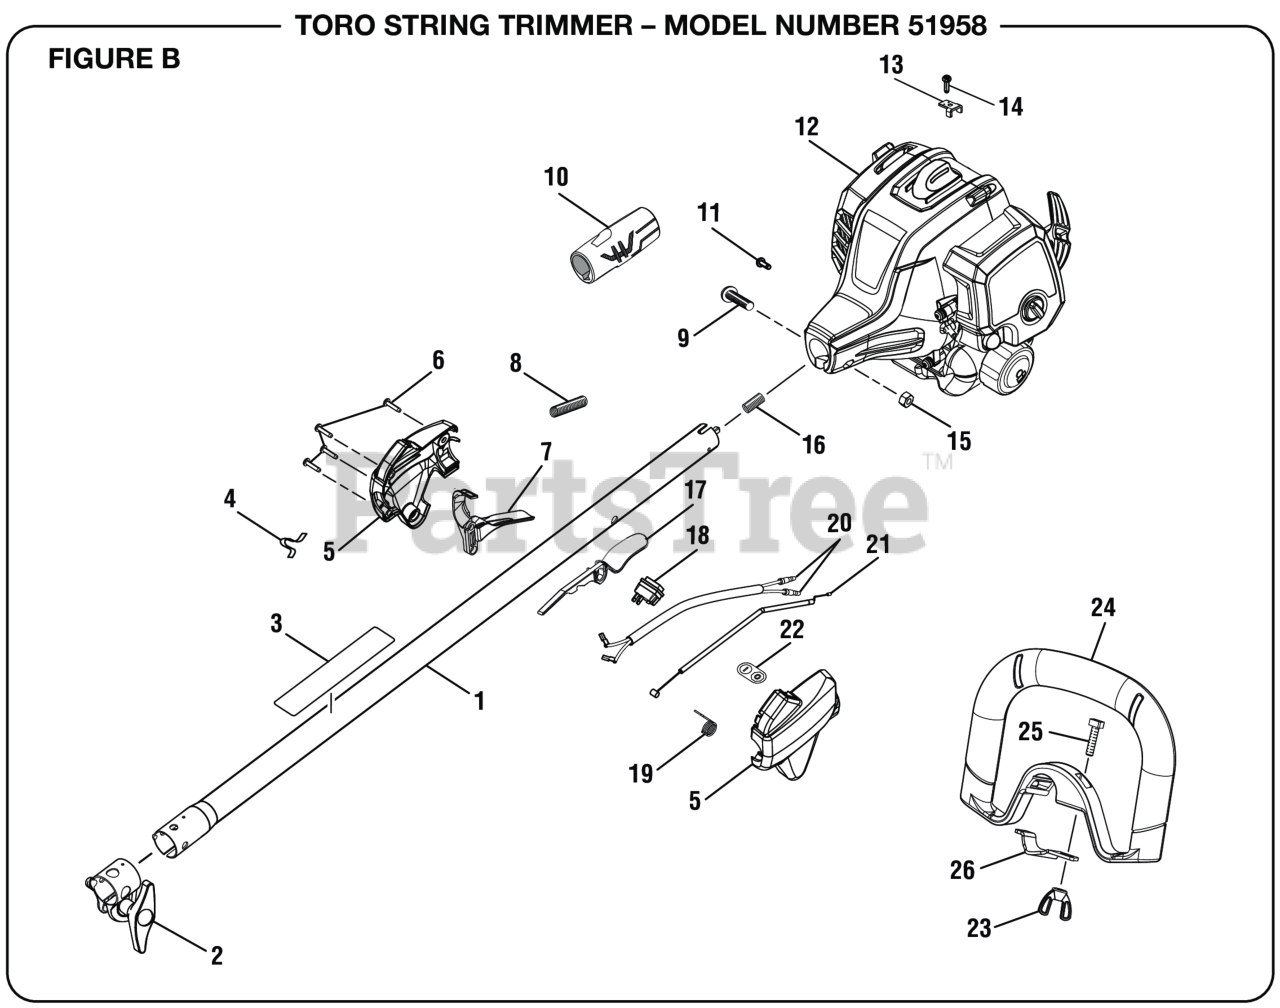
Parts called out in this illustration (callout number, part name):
1	Upper Boom Assembly
2	Boom Clamp Assembly
3	Warning Icon Label
4	Shoulder Strap Hook
5	Control Handle Assembly
6	Screw (M4 x 20 mm, T20 Torx Pan Hd. S.T.)
8	Corrugated Tube (225 mm)
9	Screw (M6 x 30 mm, T27 Torx Button Hd.)
10	Rear Handle Grip
11	Screw (M4 x 8 mm, T25 Torx Pan Hd. T.F.)
12	Powerhead Assembly
13	THROTTLE CABLE CLAMP
14	Screw (M4 x 16 mm, T20 Torx Pan Hd. S.T.)
15	Hex Nut (M6.3 x 1)
16	COMPRESSION SPRING
17	Trigger Lock
18	On/Stop Switch
19	Torsion Spring (Throttle Trigger)
20	Lead Assembly
21	Throttle Cable
22	On/Stop Label
23	Wing Nut (1/4-20, Plastic)
24	Front Handle w/Grip
25	Bolt (1/4-20 x 1 in., Square Hd.)
26	Front Handle Clamp
